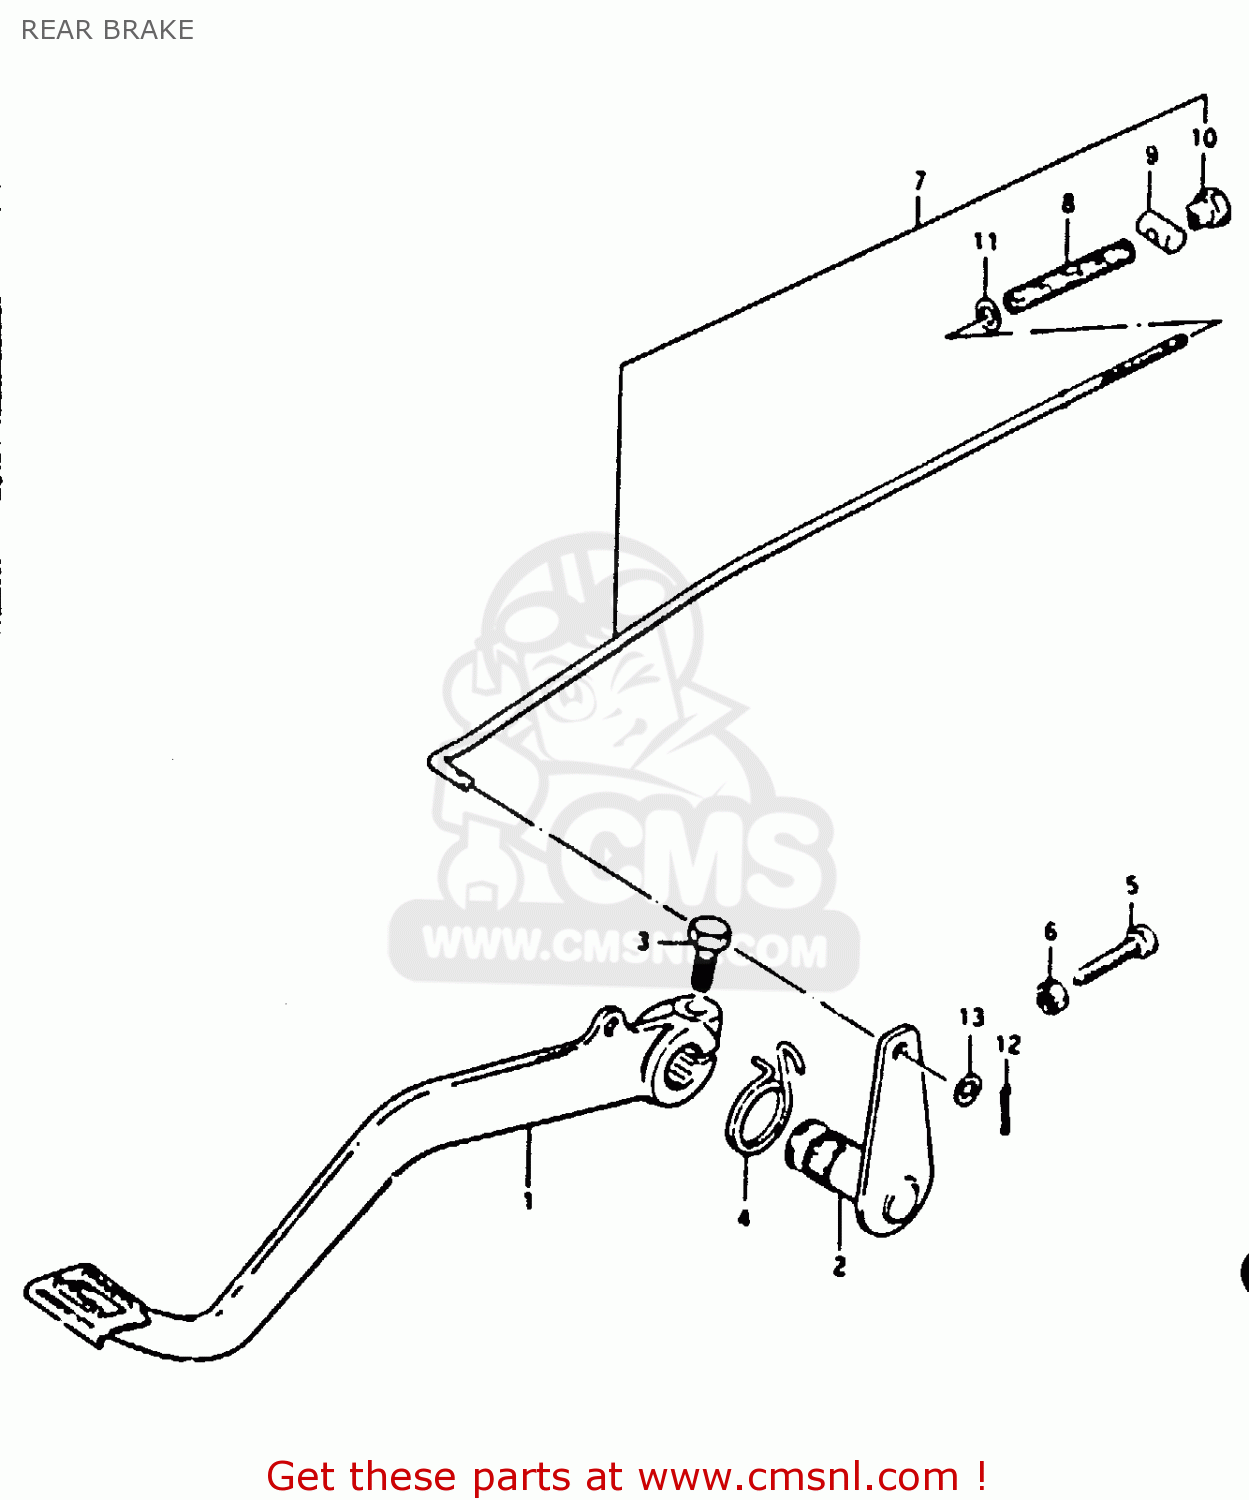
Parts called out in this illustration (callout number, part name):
1	PEDAL,BRAKE
2	ARM,BRAKE PEDAL ROD
3	BOLT
4	SPRING
5	BOLT(6X23)
6	NUT
7	ROD ASSEMBLY,REAR BRAKE
8	SPRING
9	PIN(11X18)
10	NUT
11	WASHER
12	PIN 20X20
13	WASHER
